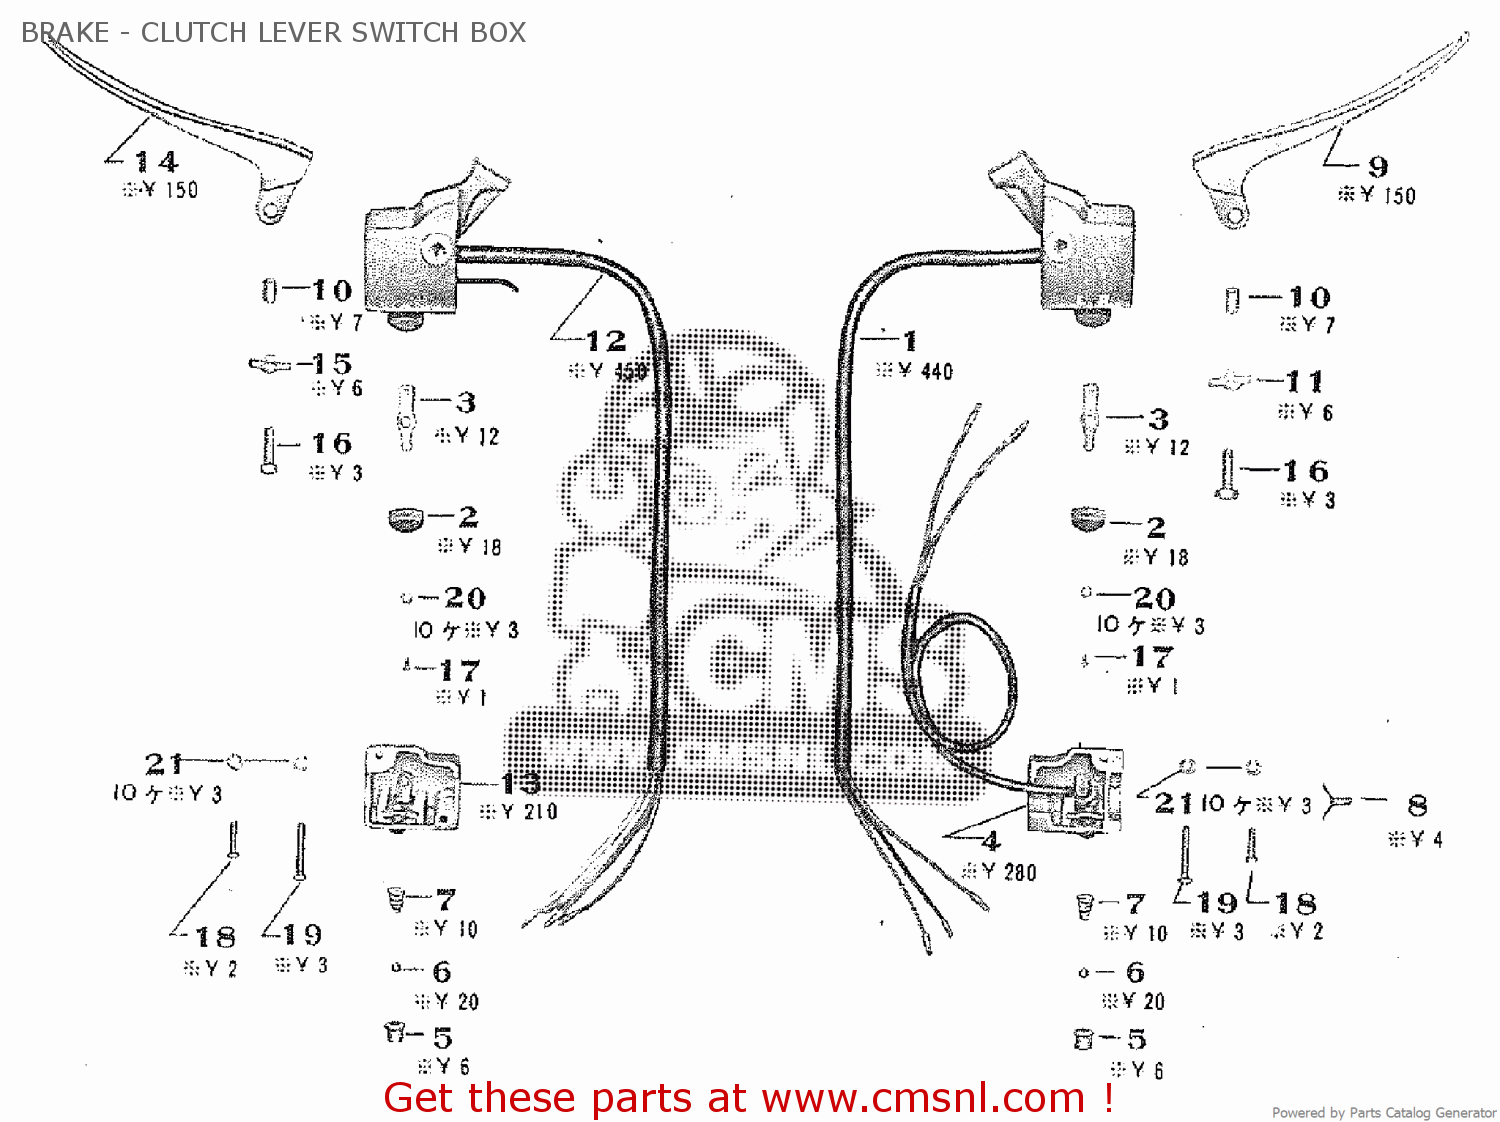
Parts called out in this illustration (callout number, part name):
1	RIGH SWITCH UPPER BOX COMP.
2	SWITCH NOB
3	SWITCH LEVER
4	RIGHT SWITCH UNDER BOX COMP.
5	BOTTON
6	BOTTON POINT COMP.
7	BOTTON SPRING
8	THROTTLE GRIP ADJUSTER SPRING
9	BRAKE LEVER
10	LEVER COLLAR
11	WASHER
12	LEFT SWITCH BOX ASSY
13	LEFT SWITCH UNDER BOX ASSY
14	CLUTCH LEVER
15	WASHER
16	6X22 HEXAGON BOLT
17	CROSS HEAD SCREW
18	CROSS HEAD SCREW
19	CROSS SCREW
20	8MM SPRING WASHER
21	5MM SPRING WASHER
